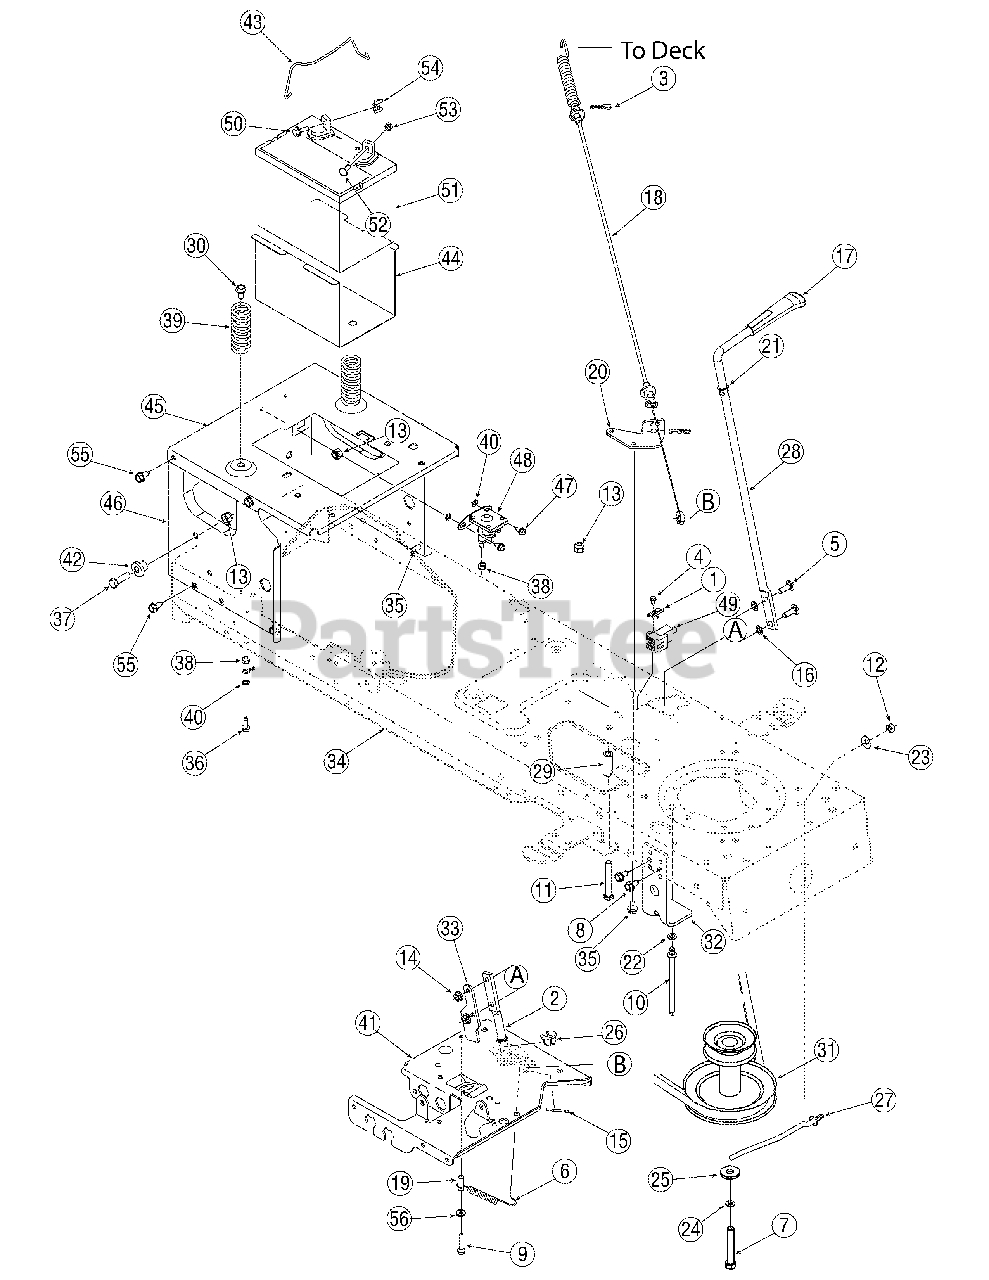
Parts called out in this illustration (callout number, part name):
1	Plate, Switch
2	Lever Assembly, Engagement
3	Click Pin
4	Screw, #10-16, 0.500
5	Screw, Carriage, 5/16-18, 1.00
6	Extension Spring, .38 OD x 3.9 Lg
7	Screw, 7/16-20, 2.75 46" Deck
7	Screw, 7/16-20, 3.25 42" Deck
8	Screw, 5/16-12, 0.750
9	Screw, 1/4-20 x 1.50
10	Pin, Belt Guard, 5/16 x 5.80
11	Screw, 3/8-16 x 2.50
12	Nut, Flange Lock, 5/16-18, GrF
13	Nut, Flange Lock, 3/8-16, GrF
14	Nut, Flange Lock, 5/16-18, Gr5
15	Pin, Cotter, 1/8 x 1.00
16	Nut, Speed, .3125 ID
18	Deck Engagement Cable
19	Spacer, .260 x .372 x 1.030 Lg.
22	Washer, Lock, 5/16
23	Washer, Bell, .340 x .872 x .060
24	Washer, Lock, 7/16
25	Washer, Flat, .450 x1.250 x.164
26	Bearing, Flange, Hex Split .500 ID
27	Keeper Rod, Belt
28	Engagement Handle, Deck
29	Spacer, .385 ID x .635 OD x 1.54
30	Screw, 5/16-18 x .750
31	Pulley, Engine, 42" Deck
31	Pulley, Engine, 46" Deck
36	Screw, 1/4-20, 0.750
37	Screw, 3/8-16, 1.25, Gr5
38	Nut, Flange Lock, 1/4-20, GrF
39	Spring, Compr., 1.28 OD x 3.125
40	Washer, Lock, 1/4, External
42	Spacer, Shoulder, .38 x 1.0 x .70
43	Hold Rod, Battery
48	Solenoid, 12V, 100 Amp
49	Switch, Interlock
50	Screw, Shoulder, .250 x .150
51	Battery, 190 CCA
51	Battery, 235 CCA
52	Hex Head Flange Screw
53	Nut, Sems, 1/4-20
54	Nut, Wing, 1/4-20
55	Screw, 5/16-18 x 0.625
56	Washer, Flat, .28 x .74 x .063
